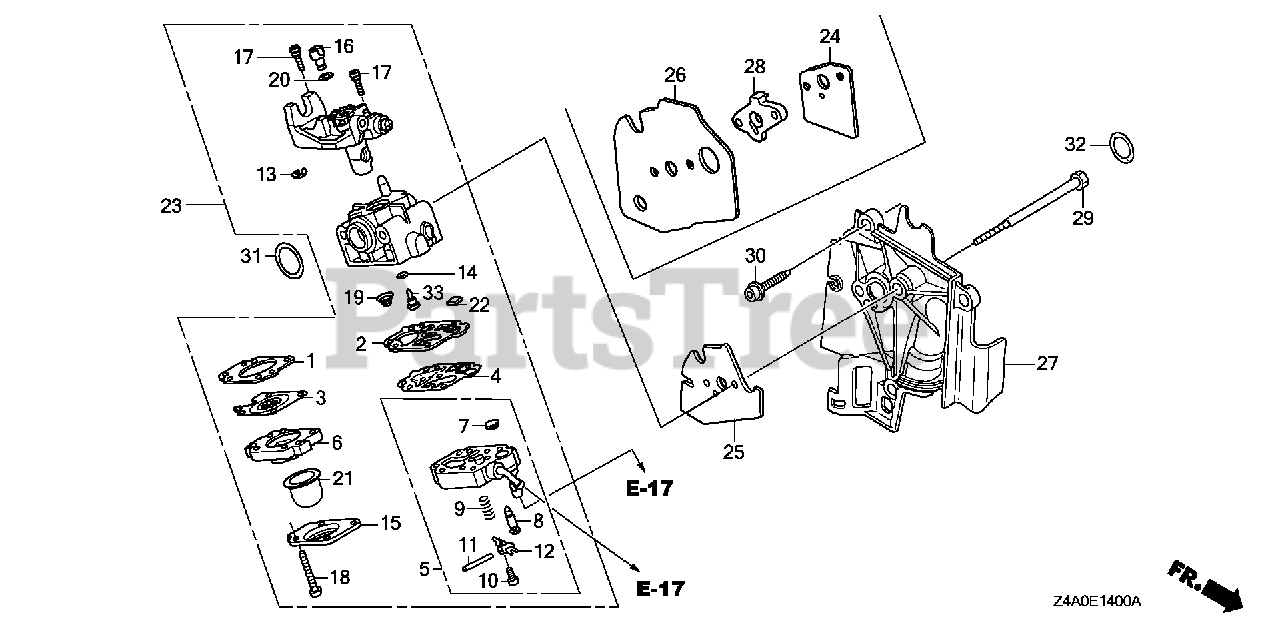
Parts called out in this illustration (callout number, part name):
1	GASKET, METERING DIAPHRAGM
2	GASKET, PUMP
3	DIAPHRAGM ASSY., METERING
4	DIAPHRAGM, PUMP
5	BODY ASSY., PUMP
6	BODY ASSY., AIR PURGE
7	SCREEN, INLET
8	VALVE, INLET NEEDLE
9	SPRING, METERING LEVER
10	SCREW, METERING LEVER PIN
11	PIN, METERING LEVER
12	LEVER, METERING
13	RING, RETAINING
15	COVER, PRIMER PUMP
17	SCREW, THROTTLE COLLAR
18	SCREW, PUMP COVER
19	SPRING, PUMP
21	PUMP, PRIMER
22	FILTER, FUEL INLET
23	CARBURETOR ASSY. (WYB 10B)
24	GASKET, CARBURETOR
26	GASKET, SHROUD
28	SPACER, SHROUD
29	BOLT (5X59)
30	BOLT, SOCKET (5X16)
31	O-RING (14.8X2.4)
32	O-RING (12.3X2.4)
33	JET (#33)
33	JET (#32)
